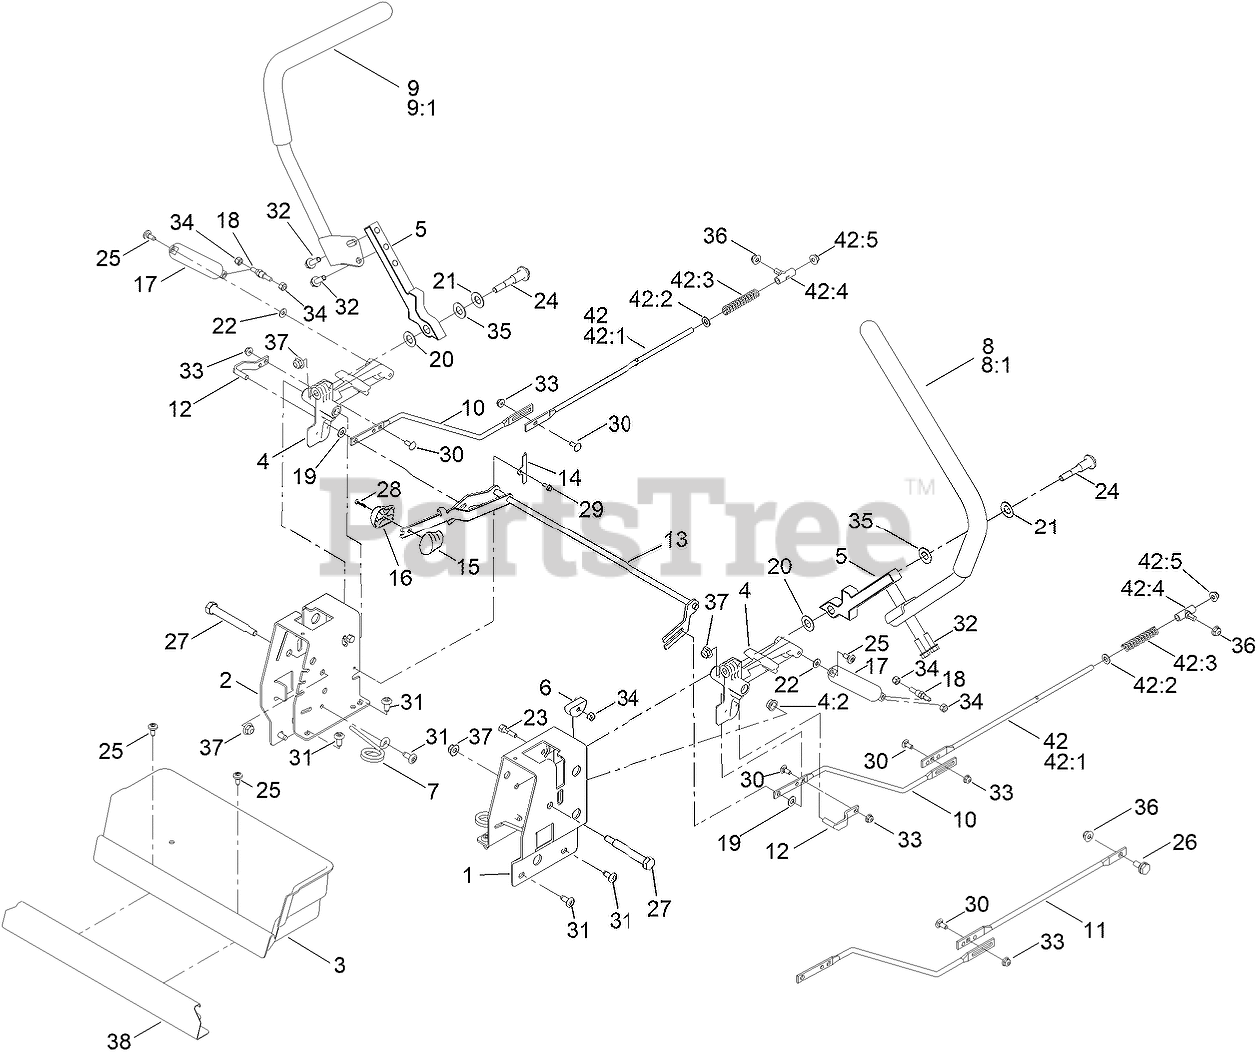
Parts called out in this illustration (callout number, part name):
1	PLATE-CONTROL BOX, LH
2	PLATE-CONTROL BOX, RH
3	BOX-STORAGE
4	ACTUATOR ARM ASM
4:2	BUSHING-FLANGE
5	ARM-CONTROL
6	ECCENTRIC
7	SPRING-TORSION
8	HANDLE-CONTROL, LH
9	HANDLE-CONTROL, RH
10	ROD-HYDRO, FRONT
11	ROD-HYDRO, REAR
12	PIN-ROD, HYDRO
13	SPEED CONTROL ASM
14	PLATE-RETAINER
15	KNOB-RH
16	KNOB-LH
17	DAMPER-NON CAVITATING
18	STUD-DAMPER
19	SPACER-NYLON
20	WASHER-NYLON
21	WASHER-BELLEVILLE
22	WASHER
23	BOLT-PIVOT, ECCENTRIC
24	BOLT-PIVOT
25	SCREW-SHOULDER
26	BOLT-SHOULDER,HFH
27	BOLT-PIVOT
28	SCREW-PPH
29	SCREW-TAPTITE
30	BOLT-CARR
32	SCREW-HHF
33	NUT-HF
34	NUT-HEX
35	WASHER
36	NUT-HF
37	NUT-HF, NI
38	PLATE-KICK
42	ROD HYDRO ASM
42:1	ROD-HYDRO, REAR
42:2	WASHER-PLAIN
42:3	SPRING-COMPRESSION
42:4	MOUNT-ROD, HYDRO
42:5	NUT-HF
